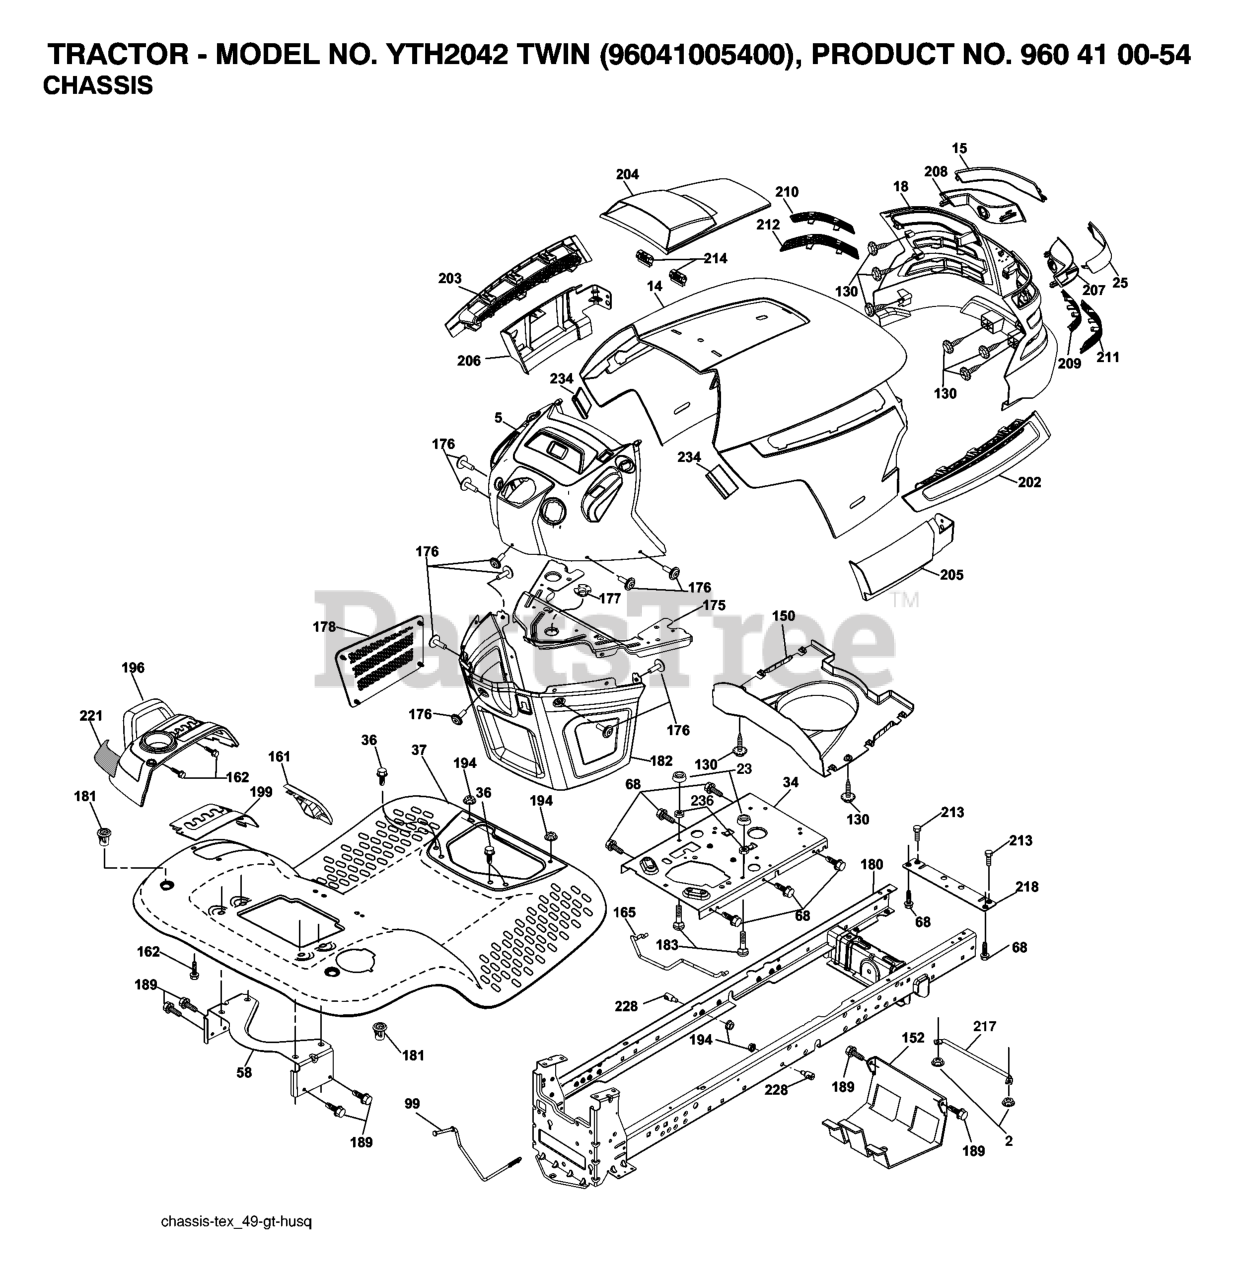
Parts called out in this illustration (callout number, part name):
5	DASH.ASM.HUSQ.GT.E.RECT.W/CK
14	HOOD
15	LENS.LH.TEX.GT.HUSQ.CL
18	GRILL.ASM.HUSQ.TG/CRD.W/TRIM
25	LENS.RH.TEX.GT.HUSQ.CL
34	PLATE.ENGINE.WELDED.CHASSIS
36	SCREW 5/16"
37	FENDER.PNT.TX.GT.CH/FW.ORANGE
52	LOCKNUT
58	BRKT.SUPPORT.FNDR/TANK
68	Screw 5/16-18 x 1/2 Hex, Self Tapping 5/16-18 x 1/2
99	ROD ASM BYPASS
130	SCREW
150	AIR.DUCT.HOOD.TEX.GT.HUSQ
152	SHIELD.BROWNING.W/TEX
161	CONSOLE.FUEL.WINDOW.HU
162	SCREW.HI-LO.CONSOLE
165	SUPPORT.TANK.REAR.W/TEX
175	PLATE.CROSSMEMBER.HUSQ
176	SCREW.#10-24X5/8.RN.QU
177	BUSHING, STEERING
178	CARGO.ASM.NET.TXGT.W/C
180	CHASSIS.WLDMT.TX.GT.05
181	BUSHING.MNT.FEND.CRGO.
182	DASH.LOWER.COMMON.12V.
183	BOLT.5/16-18X1-1/4 FULL.THREAD
189	SCREW
194	NUT LOCK HEX FLANGE 5/16-18
196	RP CONSOLE.ASM.DECKLFT.W/
199	PLATE.DECK.LIFT.HUSQVARNA.GT
202	VENT.SIDE.HOOD.HUSQ.RH.GREY
203	VENT.SIDE.HOOD.HUSQ.LH.GRAY
204	VENT.TOP.HOOD.HUSQVARN
205	SKIRT.HOOD.SIDE.HUSQ.RH.GREY
206	SKIRT.HOOD.SIDE.HUSQ.LH.GREY
207	BEZEL.RH.TEX.GT.HUSQ
208	BEZEL.LH.TEX.GT.HUSQ
209	INSERT.HEX.GRILL.HUSQ.GREY
210	INSERT.HEX.GRILL.HUSQ.
211	INSERT.HEX.GRILL.HUSQ.
212	INSERT.HEX.GRILL.HUSQ.
213	BOLT
214	CLIP.RETAINER.TINNER.
217	ROD PIVOT CHASSIS/HOOD
218	X-PIECE.HOOD.STOP.NON/
221	REFLECTOR.LH.TEX GT HU
228	STUD.FASTNER.W/ANTI-ROTATE
234	BUMPER.HOOD.TEX.HUSQVARNA
235	SPACER FENDER
236	NUT.CENTERLOCK.5/16-
